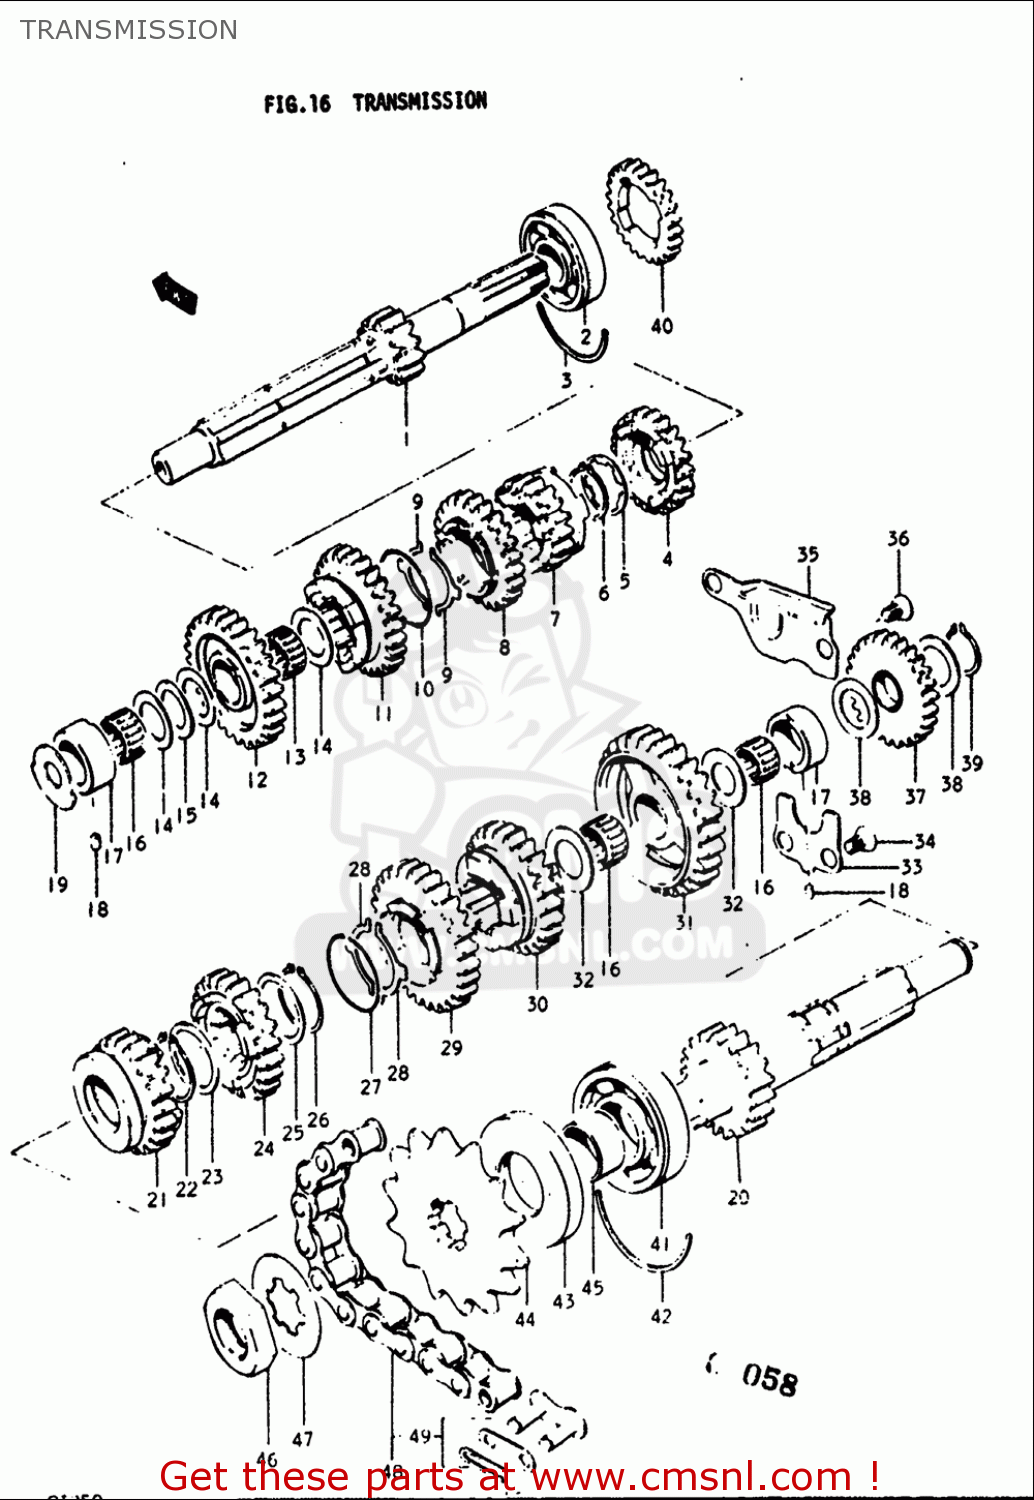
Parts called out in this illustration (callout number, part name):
2	BEARING 20X52X15
3	C RING
5	WASHER
6	RING,SNAP
10	CIRCLIP
13	BEARING(17X21X9.8)
14	WASHER
15	WASHER(17X29X1)
16	BEARING(17X21X12.8)
17	BUSHING
18	PIN
22	RING,SNAP
23	WASHER
26	RING,SNAP
27	CIRCLIP
32	WASHER(17X29X1)
36	SCREW
38	SHIM(17X30X1)
39	CIRCLIP
44	SPROCKET,ENGINE
45	SPACER (22X27X13.4)
46	NUT
47	WASHER,LOCK
48	CHAIN,DRIVE #525TR-10
49	JOINT ASSEMBLY,CHAIN
